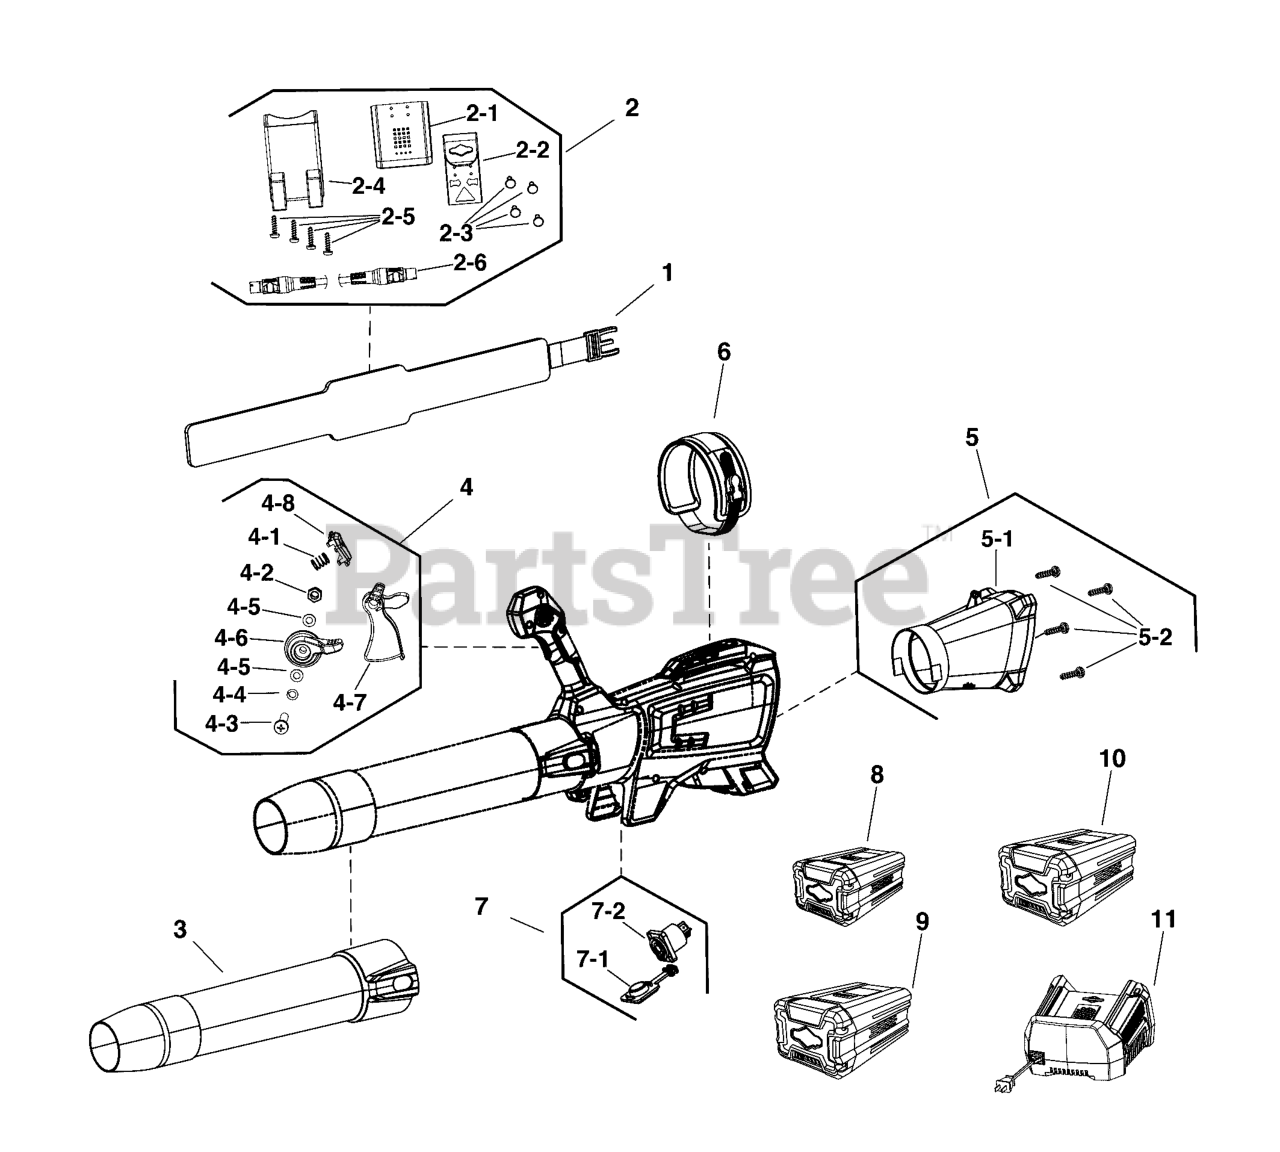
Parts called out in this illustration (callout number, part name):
1	BELT ASSEMBLY
2	KIT, Battery Pack
2-1	BRACKET, Battery Pack
2-2	BRACKET, Belt
2-4	BATTERY PACK
2-6	POWER CORD
3	TUBE ASSEMBLY
4	KIT, Trigger Switch
4-1	SPRING
4-4	SPRING WASHER
4-5	WASHER, Flat
4-6	LEVER, Speed
4-7	SWITCH, Trigger
4-8	BUTTON, On/Off
5	KIT, Cover, Rear
5-1	COVER, Rear
5-2	SCREW
6	KIT, Strap
7	KIT, Outlet
7-1	OUTLET
7-2	COVER, Outlet
8	* BATTERY, 2.0, 82V NA
9	* BATTERY, 4.0, 82V NA
10	* BATTERY, 5.0, 82V NA
11	* CHARGER, Battery, NA
